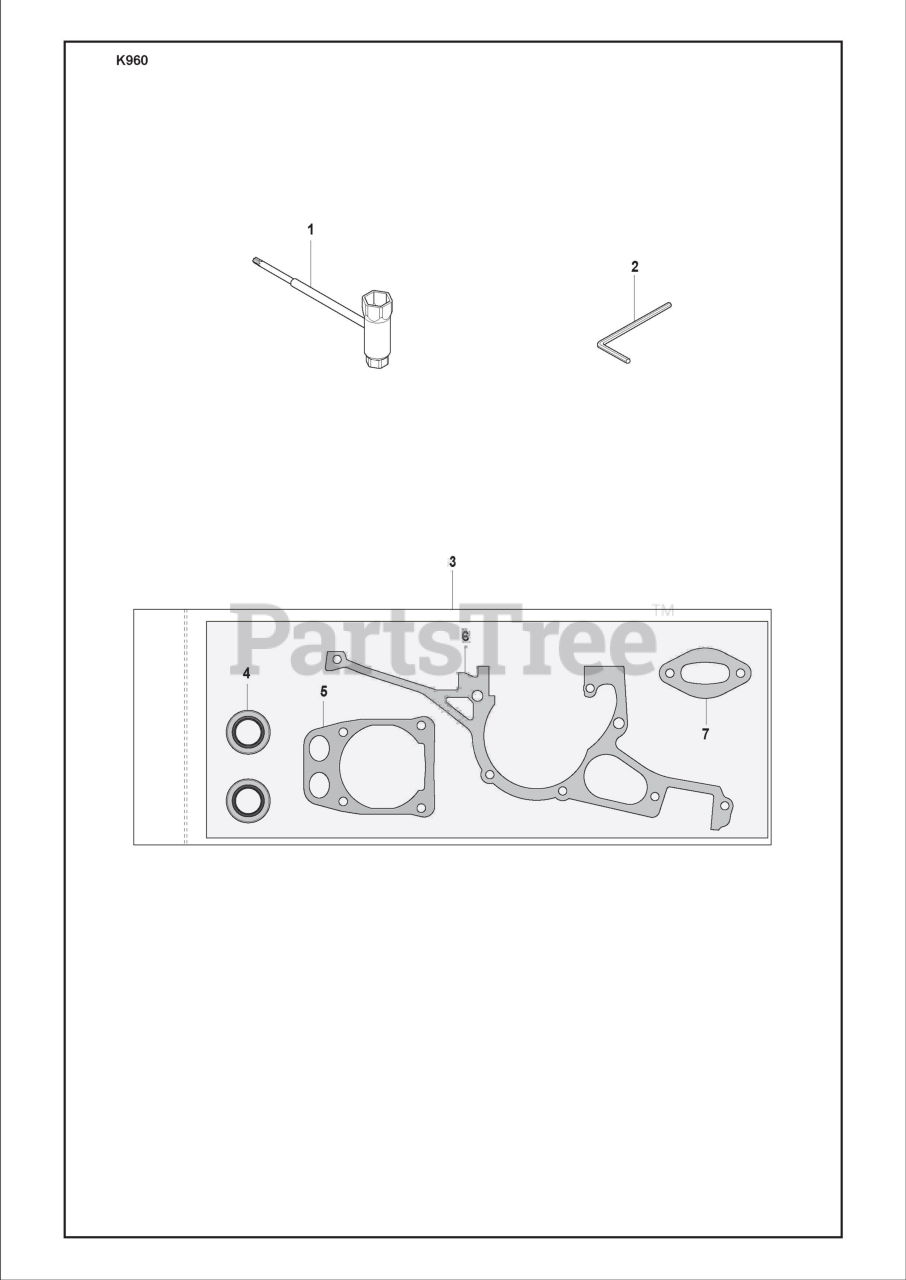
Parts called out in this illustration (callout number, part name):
1	Combination Tool
2	L-Spanner
3	Gasket Kit
4	Sealing Ring
5	Gasket
6	Gasket
7	Gasket Muffler
